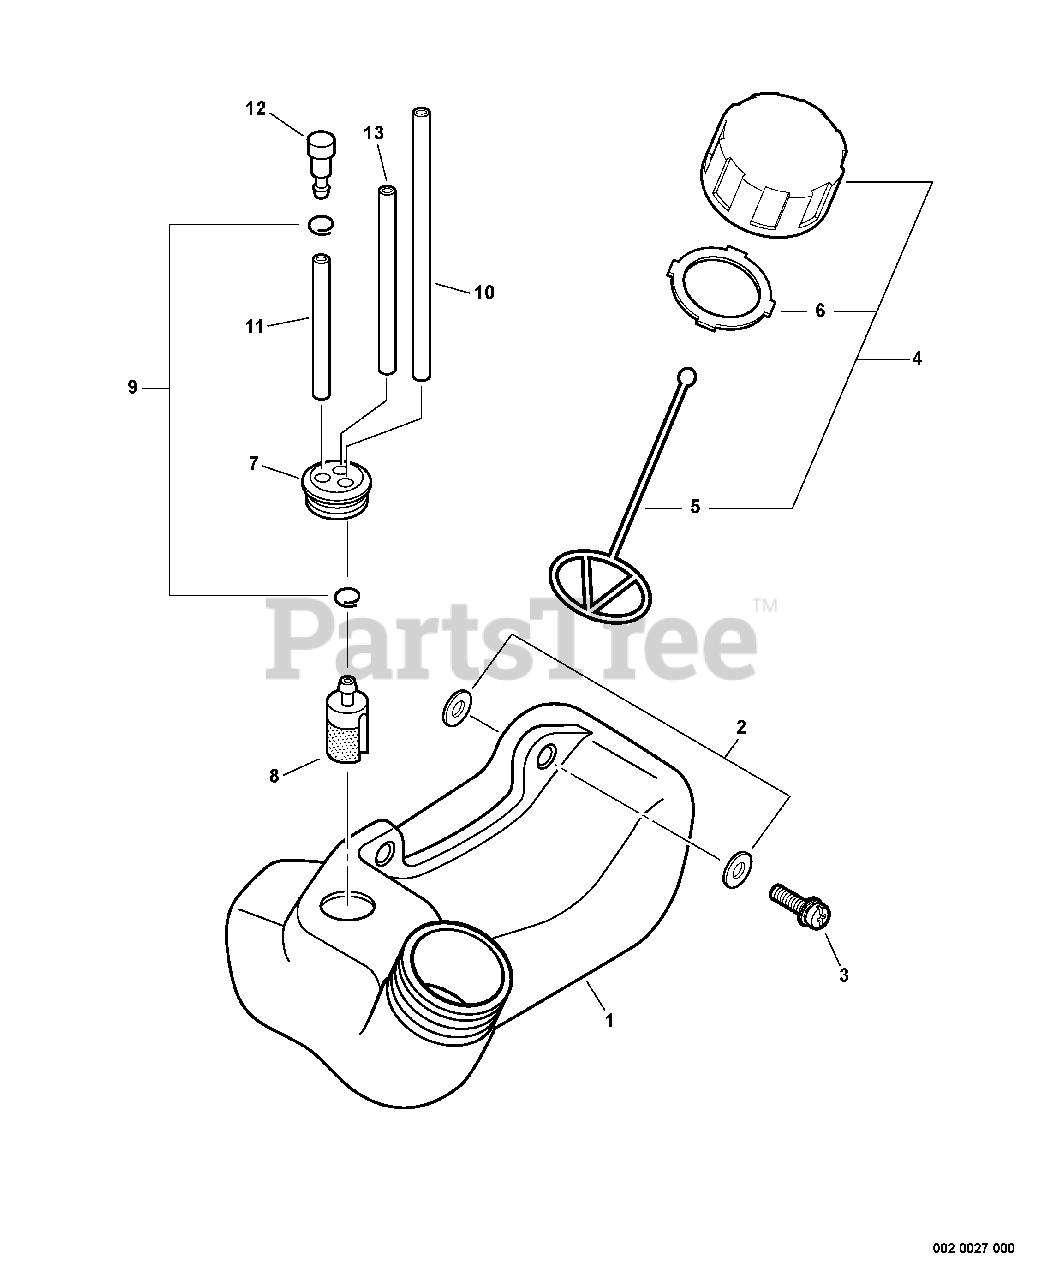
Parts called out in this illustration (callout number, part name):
1	TANK, FUEL
2	WASHER 8
3	SCREW 5×25
4	CAP ASSY, FUEL
5	CONNECTOR, FUEL CAP
6	GASKET, FUEL CAP
7	GROMMET, FUEL
8	FILTER, FUEL
9	CLIP 6 MM
10	PIPE, FUEL 3×5×195 BLACK
11	PIPE, FUEL
12	VENT ASSY
13	PIPE, FUEL RETURN 3×6×110
